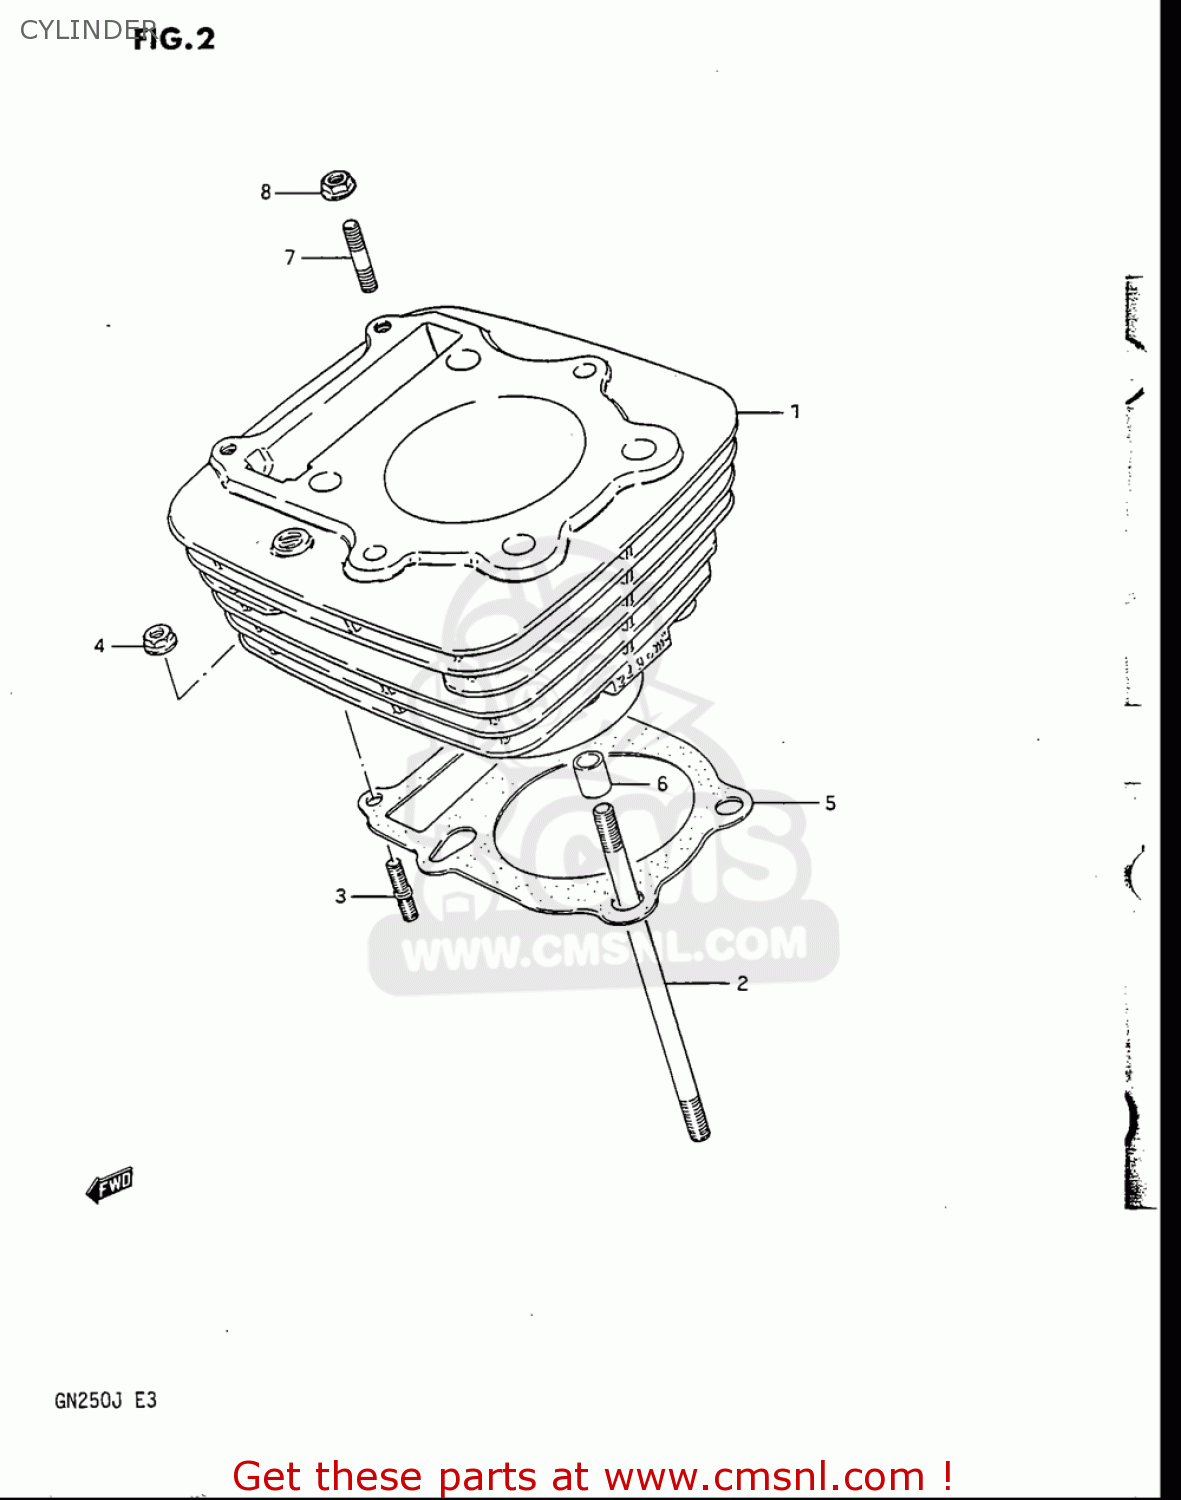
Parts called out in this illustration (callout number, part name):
1	CYLINDER
2	BOLT,STUD
3	BOLT,STUD
4	NUT
5	GASKET,CYLINDER (NAS)
6	PIN
7	BOLT,STUD
8	NUT
